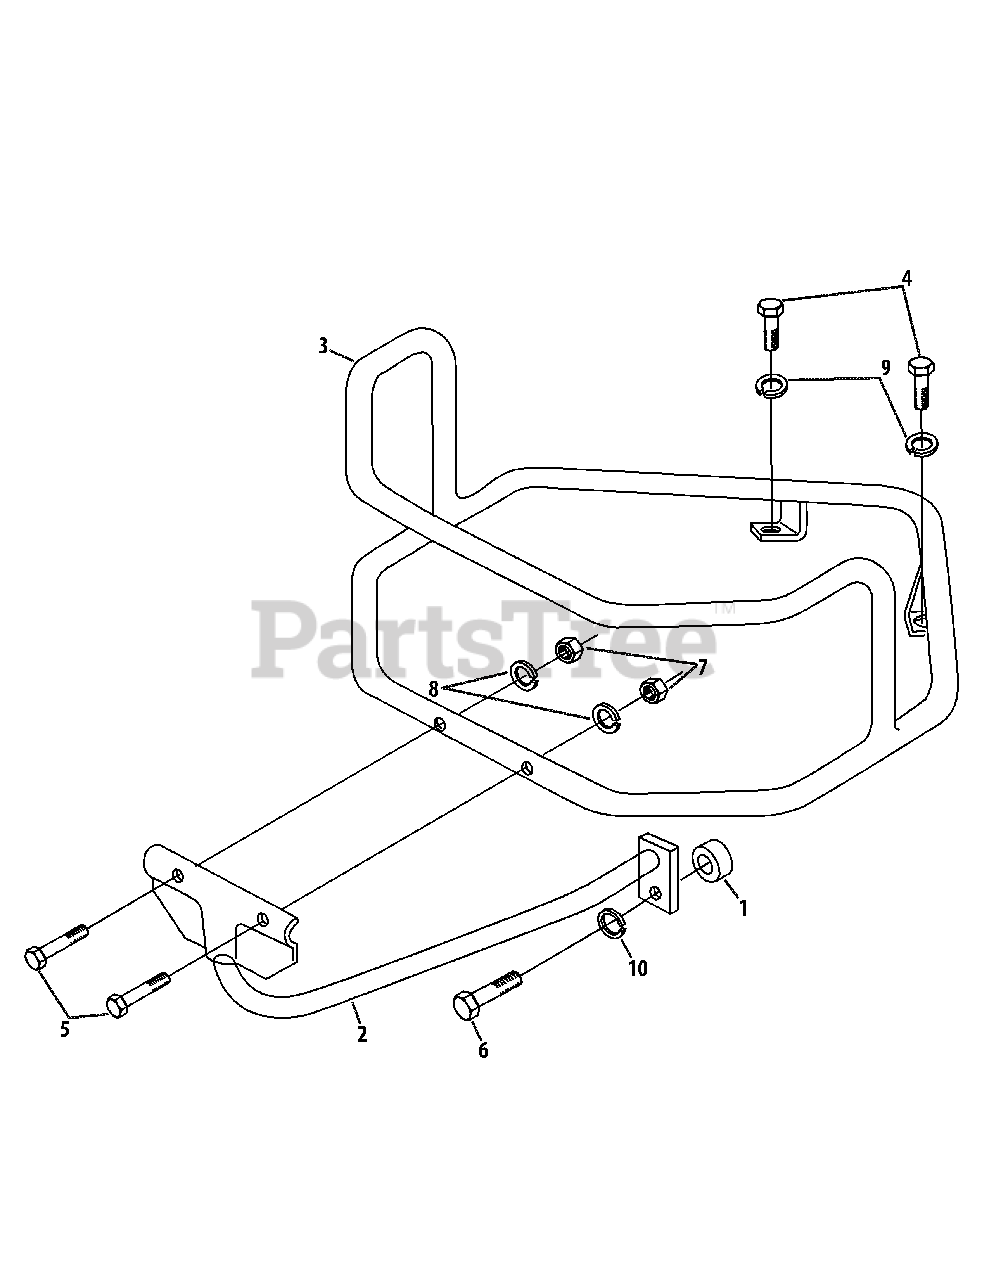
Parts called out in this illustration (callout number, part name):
1	Spacer, 1.0 x .546 x .5
2	Bottom Bumper Brace
3	Bumper Guard
4	Hex Screw, 3/8"-16 x 1.00
5	Hex Screw, 5/16"-18 x 1.50
6	Hex Screw, 1/2"-13 x 1.50
7	Hex Nut, 5/16"-18
8	Lock Washer, 5/16"
9	Lock Washer, 3/8"
10	Lock Washer, 1/2"
